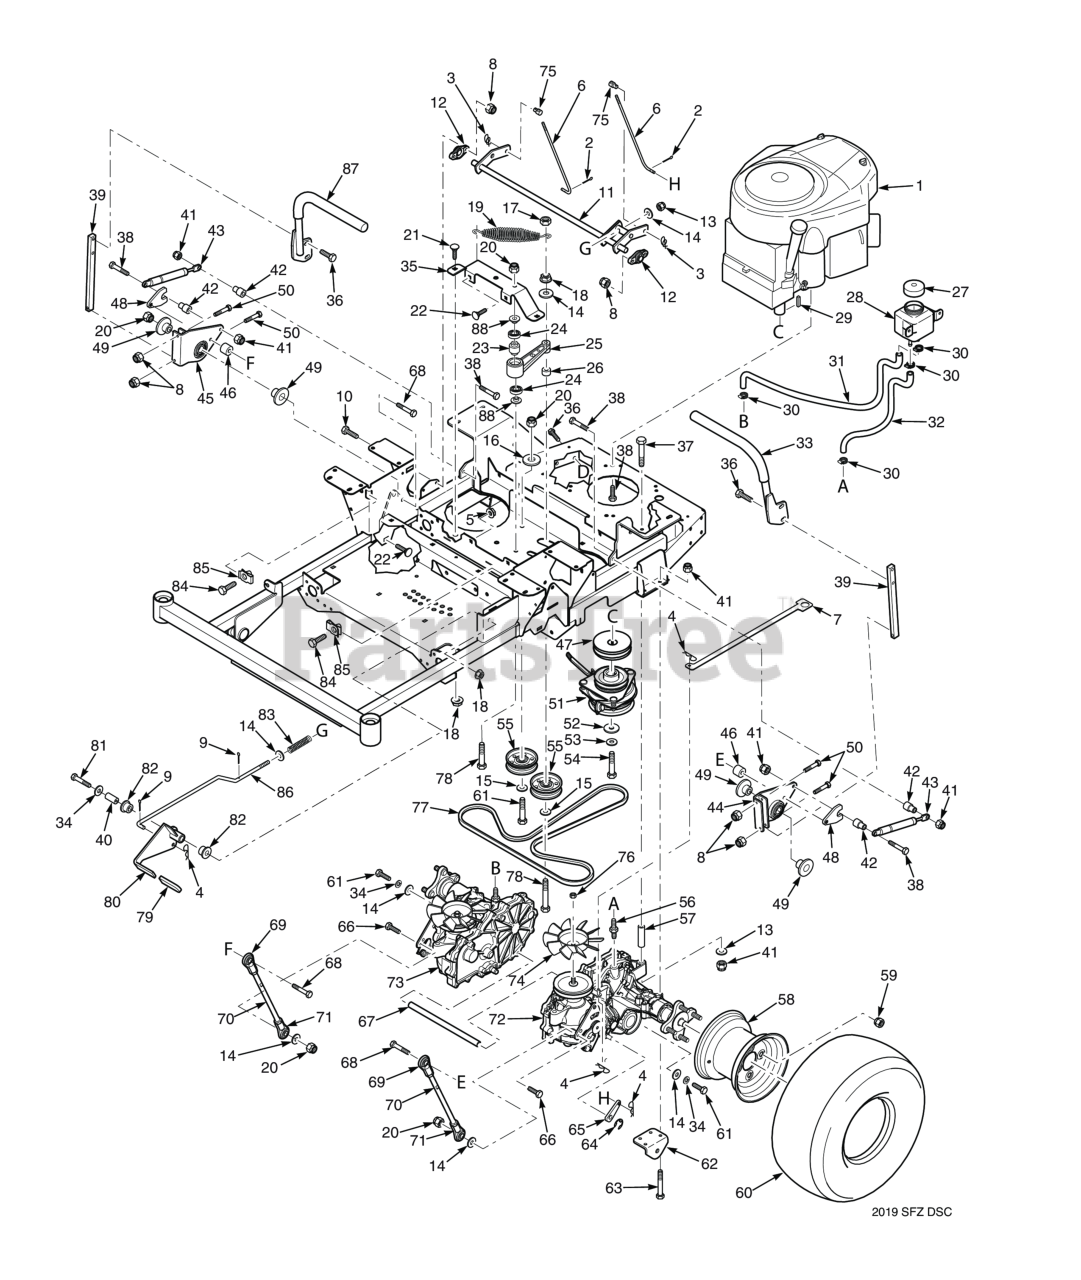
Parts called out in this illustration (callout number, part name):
1	Engine, Kohler 22KT
1	Engine, Kohler 24KT
2	COTTER PIN, 3/32 X 1"
3	Pin, Rue Cotter 3/8" Diameter
4	HAIR PIN, .08 DIAMETER X 1-3/16"
5	Nut, Serrated Flange 5/16-18 (Right Front Engine Mounting, Briggs and Kohler Only)
6	Rod, Brake Adjustment
7	Lever, Dump Valve
8	Nut, Flanged Elastic Stop 1/4-20
9	COTTER PIN, HAIR - 0.94 X 1.62
10	CAP SCREW, 1/4-20 X 1" SERRATED FLANGE HEX
11	Weldment, Brake Lever
12	Bearing
13	Flatwasher, 5/16-.375 x .875 x .083 (35BV & 37BV-EFI)
14	Flatwasher, 3/8" Special (.391 x .938 x .105)
15	Flatwasher, 3/8 (.391 x .938 x .105 HD) Grade 8
16	Flatwasher, 3/8-.406 x 1-1-1/2 x 7 Gauge
17	Bolt, Hex Head 3/8-16 x 1" Ser. Flg.
18	NUT, 3/8-16 SERRATED FLANGE HEX HEAD
19	Spring, Transmission Idler
20	HEX NUT, ELASTIC STOP LOCK, 3/8-16
21	Bolt, Carriage 3/8-16 x 3/4"
22	Bolt, 5/16-18 x .75 RHSN Carriage
23	Spacer, Bearing
24	BEARINGS, BALL, NEUTRAL RETURN
25	Trans. Idler Arm Assy. (Includes 24, 79)
26	Spacer, Idler Pulley - SFZ52
27	Cap, Hydraulic Tank
28	Reservoir Assembly
29	KEY, 1/4 X 1/4 X 3/4"
30	Clamp, Cable 3/4" I.D.
31	Hose, RH Transmission
32	Hose, LH Transmission
33	Handle Bar Assembly LH, w/Grip
33	Grip, Control Handle
34	Flatwasher, 3/8" Special (.391 x .938 x .105)
35	Support, Idler Arm
36	Capscrew, 3/8-16 x 1.0" Serrated Flange Hex Hd
37	HEX HEAD BOLT, 5/16-18 X 5"
38	Bolt, Hex Head 5/16-18 x 1-1/2" (Right Front Engine Mounting, Briggs and Kohler Only)
38	Screw, 1/4-20 x .375"
39	Bar, Control Lever
40	Pivot, Brake Lever
41	HEX NUT, ELASTIC STOP LOCK, 5/16-18
42	Spacer, Pump Dampener
43	Damper, Steering
44	Control Link, LH
45	Control Link, RH
46	Spacer, Idler Pulley - SFZ52
47	Pulley, 4-1/2" Dia. 1" Bore
48	Nut, Control Linkage
49	Spacer, Linkage
50	Bolt, Hex Head, 1/4-20 x 1-1/2"
51	Electric Clutch Assembly
51	KEY, 1/4 X 1/4 X 3/4"
52	Flatwasher, 7/16-.469 x 1.75 x .25 (48, 52)
53	Lockwasher, 7/16� Spring
54	Bolt, Hex Head 7/16-20 x 2-1/4" w/Patch (Kawasaki)
55	Pulley, 3-1/2" Dia.
56	Fitting, Transmission - SFZ61
57	Spacer, Axle - SFZ52
58	Rim w/Valve Stem
59	Wheel Nut, 1/2-20 x 13/16
60	Wheel Assembly (INCL.58)
60	TIRE, 20 X 10.0-10
61	Capscrew, Hex Head 3/8-16 x 2-1/2"
62	Bracket, Push Arm Link
63	Bolt, Hex Head 5/16-18 x 3.00"
64	Ring, Retaining External .375"
65	Lever, Brake (order through Hydro-Gear)
66	Bolt, Hex Head, 3/8-16 x 1-1/2"
67	Spacer, Axles
68	Capscrew, Hex Head 3/8-16 x 2.0"
69	Rod End, 3/8-24 UNF LH
70	Linkage, Pump
71	Rod End, 3/8-24 UNF RH
72	Transaxle Assy., LH
73	Transaxle Assy., RH
74	Fan (order through Hydro-Gear)
75	Joint, Swivel
76	Fan Nut (order through Hydro-Gear)
77	Belt, Transmission Drive - SFZ52
78	Capscrew, Hex Head 3/8-16 x 3.25"
79	Grip, Brake Handle
80	Brake Handle Assembly
81	Capscrew, Hex Head 3/8-16 x 2-1/2"
82	Bearing
83	Spring, Brake
84	Bolt, Hex Head 3/8-16 x 1-1/4" Special Lock
85	U-Nut, 3/8-16 (short)
86	Rod, Brake Linkage
87	Handle Bar Assembly RH, w/Grip
87	Grip, Control Handle
88	Spacer, Controls
